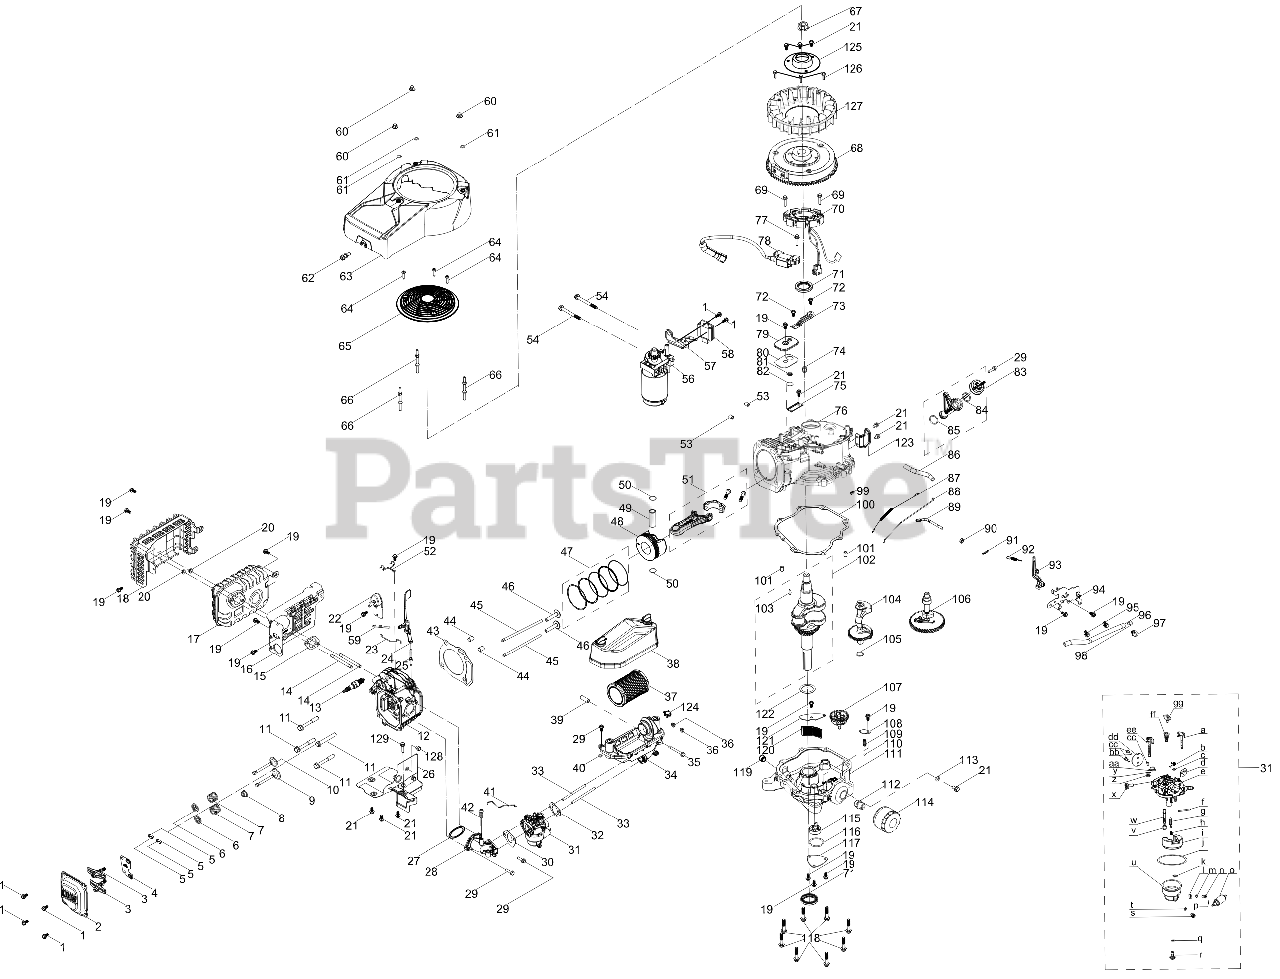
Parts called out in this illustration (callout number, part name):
1	BOLT M6 x 16
2	VALVE COVER
3	ROCKER ARM ASSEMBLY
4	ROCKER ARM BASE
5	VALVE CAP
6	VALVE SPRING SEAT
7	VALVE SPRING
8	INTAKE VALVE SEAL
9	INTAKE VALVE
10	EXHAUST VALVE
11	BOLT M10-1.25 x 70
12	CYLINDER HEAD
13	SPARK PLUG
14	STUD - M8 x 102
15	EXHAUST GASKET
16	ENGINE SHROUD
18	MUFFLER GUARD
19	BOLT M6-1 x 14 GR8.8
21	BOLT M6-1 x 12 GR8.8
22	THERMAL SWITCH
23	THERMAL LEVER
24	SHIELD ASSEMBLY
25	PIVOT VANE STUD
27	O-RING 36 x 2.5
28	INTAKE MANIFOLD
29	BOLT M6 x 22
30	INTAKE GASKET
31	CARBURETOR
32	AIR FLTER GASKET
33	STUD M6-1.00 x 92
34	AIR FILTER BASE ASSEMBLY
35	SCREW M6-1:50:CL5.
37	AIR FILTER W/PREFILTER
38	AIR FILTER COVER ASSEMBLY
39	BUSHING - 11X6X30
40	CARB FUEL DRAIN GASKET
41	CHOKE LEVER
42	SELF TAPPING SCREW 4.8 x 16
43	CYLINDER HEAD GASKET
45	PUSH ROD - INDIVIDUAL
46	TAPPET
47	PISTON RING SET
49	PISTON PIN
50	PISTON PIN SNAP RING
51	CONNECTING ROD ASSEMBLY
54	BOLT M8-1.25 x 80
56	ELECTRIC STARTER ASSEMBLY
59	IDLE SPRING
60	ACORN NUT
64	BOLT 5.5 x 25
65	FLYWHEEL SCREEN
66	STUD M6X95
67	NUT M20 x 1.5
69	BOLT M5 x 28
70	ALTERNATOR
71	OIL SEAL - 35X52X7
72	BOLT M5-.8 x 10
73	WIRE PLATE
75	BREATHER SCREEN
77	BOLT-M6-1 x 28 GR8.8
78	IGNITION COIL
79	BREATHER COVER
80	BREATHER COVER GASKET
81	BREATHER VALVE SPRING
82	BREATHER VALVE
83	DIPSTICK ASSEMBLY
86	BREATHER HOSE
87	THROTTLE DAMPENING SPRING
88	THROTTLE LINKAGE
89	GOVERNOR GEAR SHAFT
90	GOVERNOR SEAL
91	COTTER PIN
92	GOVERNOR SPRING
93	GOVERNOR ARM ASSEMBLY
94	CONTROL BRACKET ASSEMBLY
95	HOSE CLAMP
96	FUEL HOSE 6.3 x 12.5 x 250
97	FUEL LINE SUPPORT CLAMP
100	CRANKCASE GASKET
101	DOWEL PIN
102	CRANKSHAFT
103	FLYWHEEL KEY
104	BALANCE SHAFT
105	WASHER 17.2 x 26 x 1
106	CAMSHAFT ASSEMBLY
107	GOVERNOR GEAR
108	PRESSURE RELEASE COVER
109	PRESSURE RELEASE SPRING
110	OIL PUMP STEEL BALL
111	CRANKCASE COVER
112	SCREW JOINT OIL FILTER ADAPTER
113	WASHER - 6.2X1.5X13
114	ENGINE OIL FILTER
115	OIL PUMP ASSEMBLY
117	OIL SEPARATOR
118	BOLT M8 x 40
119	ENGINE PLUG 3/8 NPT
120	FILTER SCREEN
121	OIL SCREEN PLATE
122	WASHER - 35.4X1X52
125	FLYWHEEL HUB COVER
126	BOLT M5 x 18
127	COOLING FAN
128	BOLT M6-1 x 10 GR8.8
129	BOLT M6-1 x 25 GR8.8
